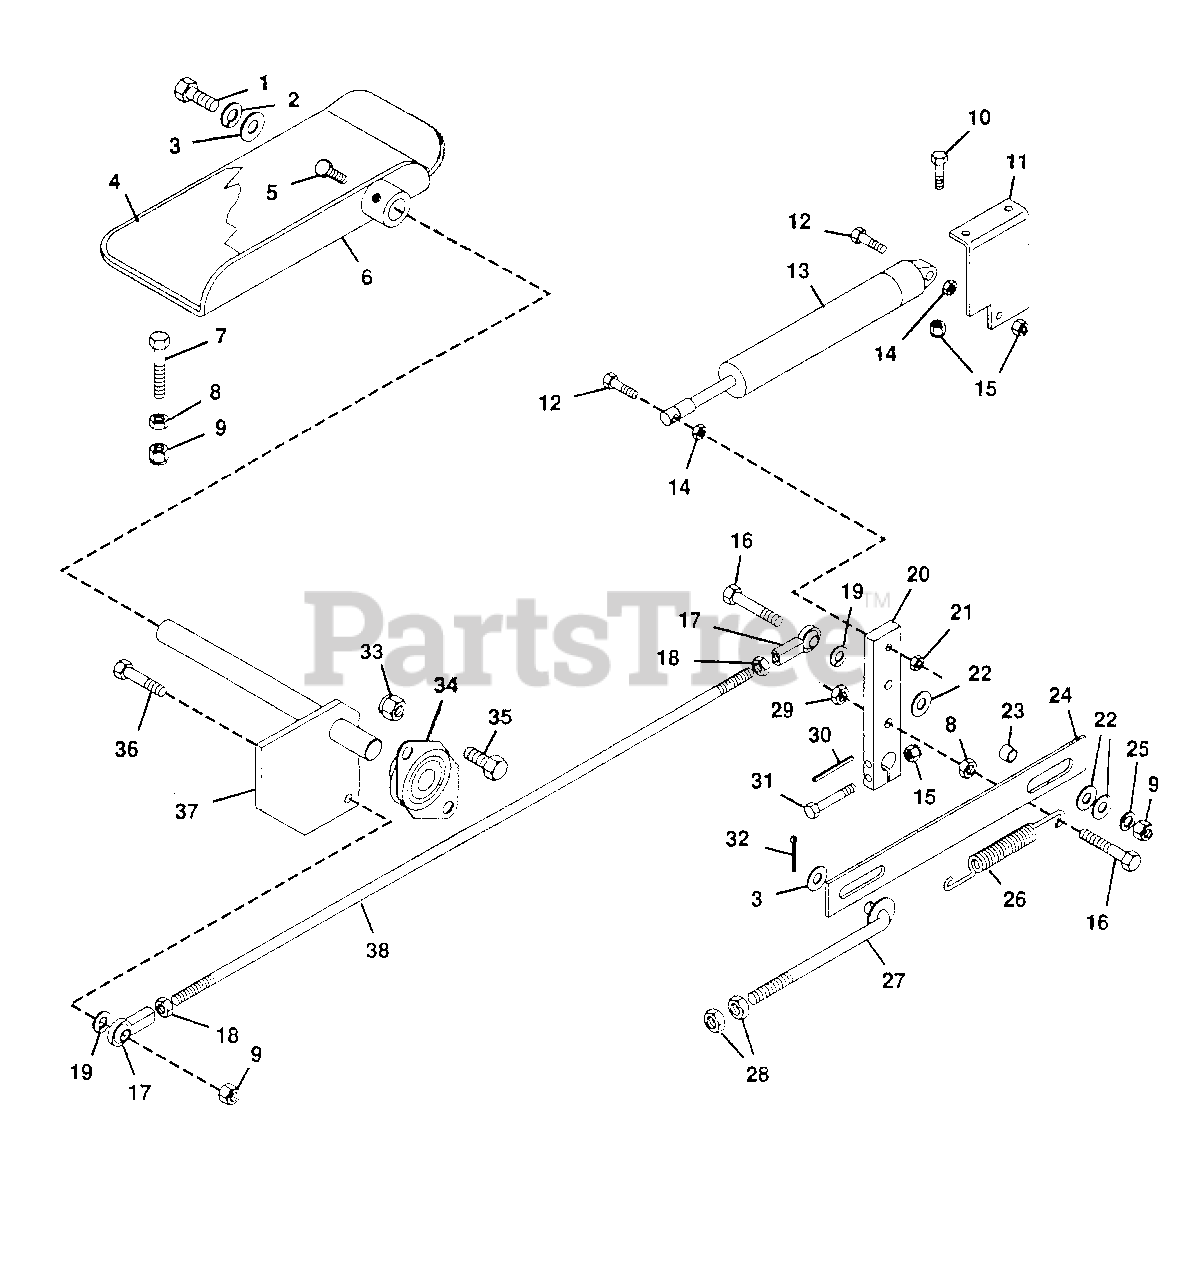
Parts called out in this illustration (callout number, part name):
1	Bolt, Hex 3/8-16x1.00
2	Washer, Lock 3/8 Reg.
3	Washer, Flat .406x.812x.065
4	Cover, Large Footboard
5	Bolt, Hex 1/4-28x.50
6	Weldment, Foot Control Lever
7	Bolt, 5/16-18x2.50 All Thread
8	Nut, Hex 5/16-18
9	Nut, Lock 5/16-18
10	Bolt, Hex 1/4-20x.625
11	Bracket, Damper
12	Bolt, Hex 1/4-20x1.50
13	Damper
14	Nut, Hex 1/4-20
15	Nut, Lock 1/4-20
16	Bolt, Hex 5/16-18x2.00
17	Rod End, 5/16 Female
18	Nut, Jam 5/16-24 Hex
19	Washer, Lock 5/16 Reg.
20	Arm, Pump
21	Nut, Lock 1/4-20
22	Washer, Flat .531x1.062x.095
23	Bush., St. .328x.500x.500 Stl.
24	Strap, Neutral Detent
25	Washer, Flat .344x.688x.065
26	Spring, Extension 5.5x.5x 20 Rate
27	Weldment, Detent Rod
28	Nut, Hex 3/8-24
29	Nut, Lock 5/16-18
30	Pin, Spring .250x1.000
31	Bolt, Hex 1/4-20x1.75
32	Pin, Cotter .094x.75
33	Nut, Lock 3/8-16
34	Bearing, Fan
35	Bolt, Hex 3/8-16x.75
36	Bolt, Hex 5/16-18x1.25
37	Weldment, Control
38	Rod, Speed Control
